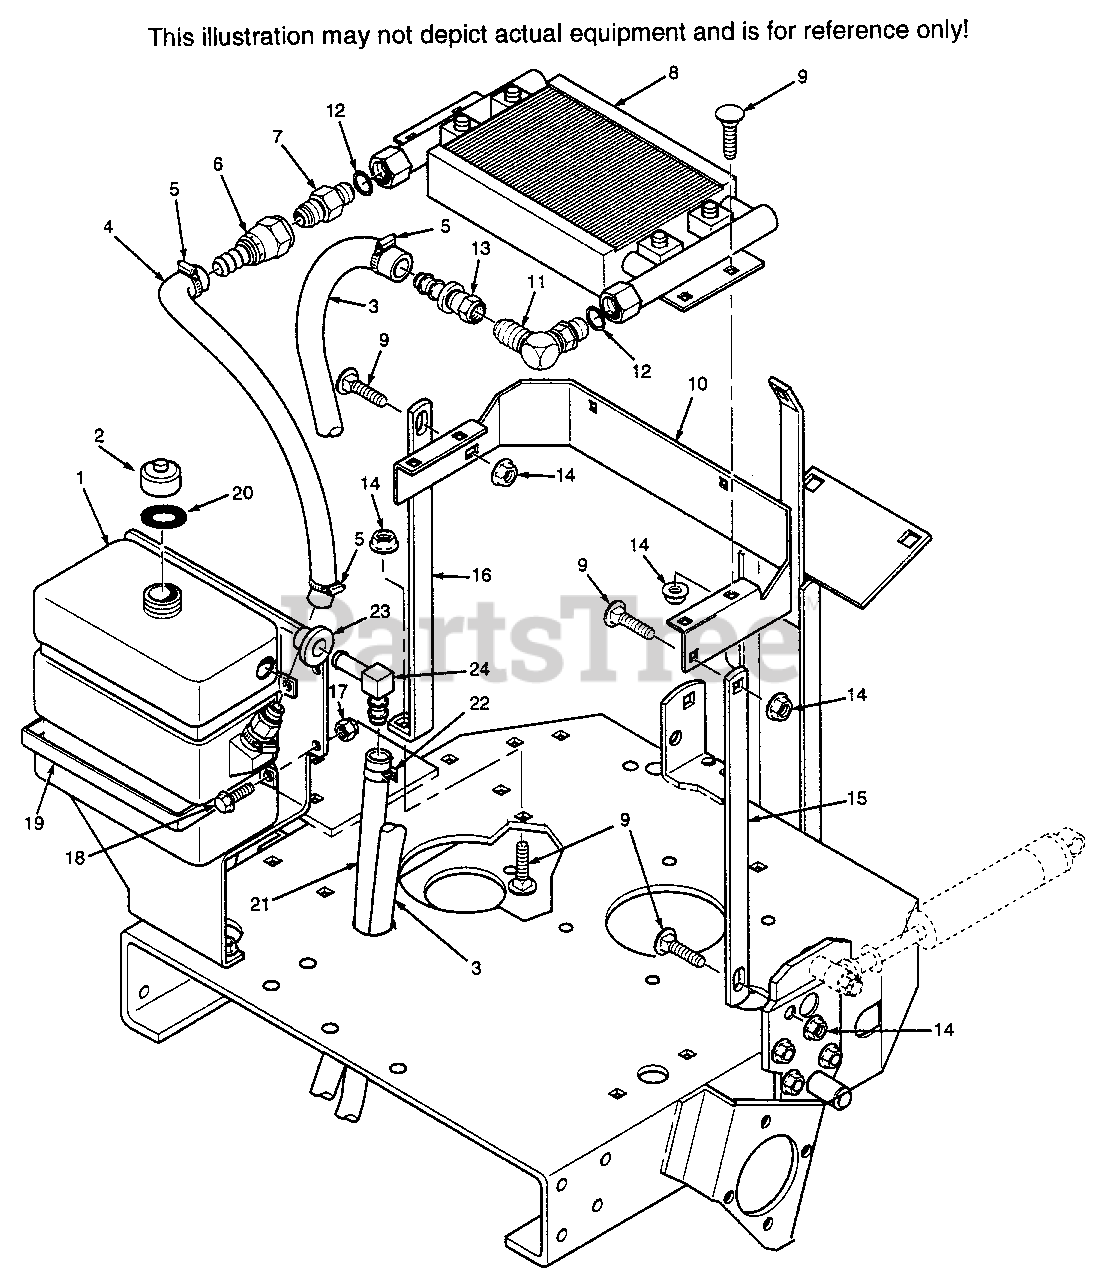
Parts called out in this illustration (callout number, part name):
1	TANK, HYDRAULIC
2	CAP, HYDRAULIC TANK
3	HOSE, PUMP TO OIL COOLER
4	HOSE, OIL COOLER TO TANK
5	CLAMP, HOSE
6	COUPLING, FLARE SWIVEL
7	TUBE, UNION
8	OIL COOLER ASSEMBLY
9	CARRIAGE BOLT, 5/16-18 X 3/4
10	BRACKET, OIL COOLER
11	ELBOW, 90 DEGREES
12	O-RING
13	COUPLING FLARE SWIVEL
14	SERR. FL. HEX HEAD NUT, 5/16-18
15	BRACE, L.H. COOLER SUPPORT
16	BRACE, R.H. COOLER SUPPORT
17	ELASTIC STOP NUT, 1/4-20
18	SERR. FL. HEX HEAD CPSCR, 1/4-20 X 3/4
19	STRAP, OIL TANK
20	GASKET, RUBBER
21	HOSE, 1/4" PUSHLOK X 27
23	BUSHING
24	90 DEGREE ELBOW
